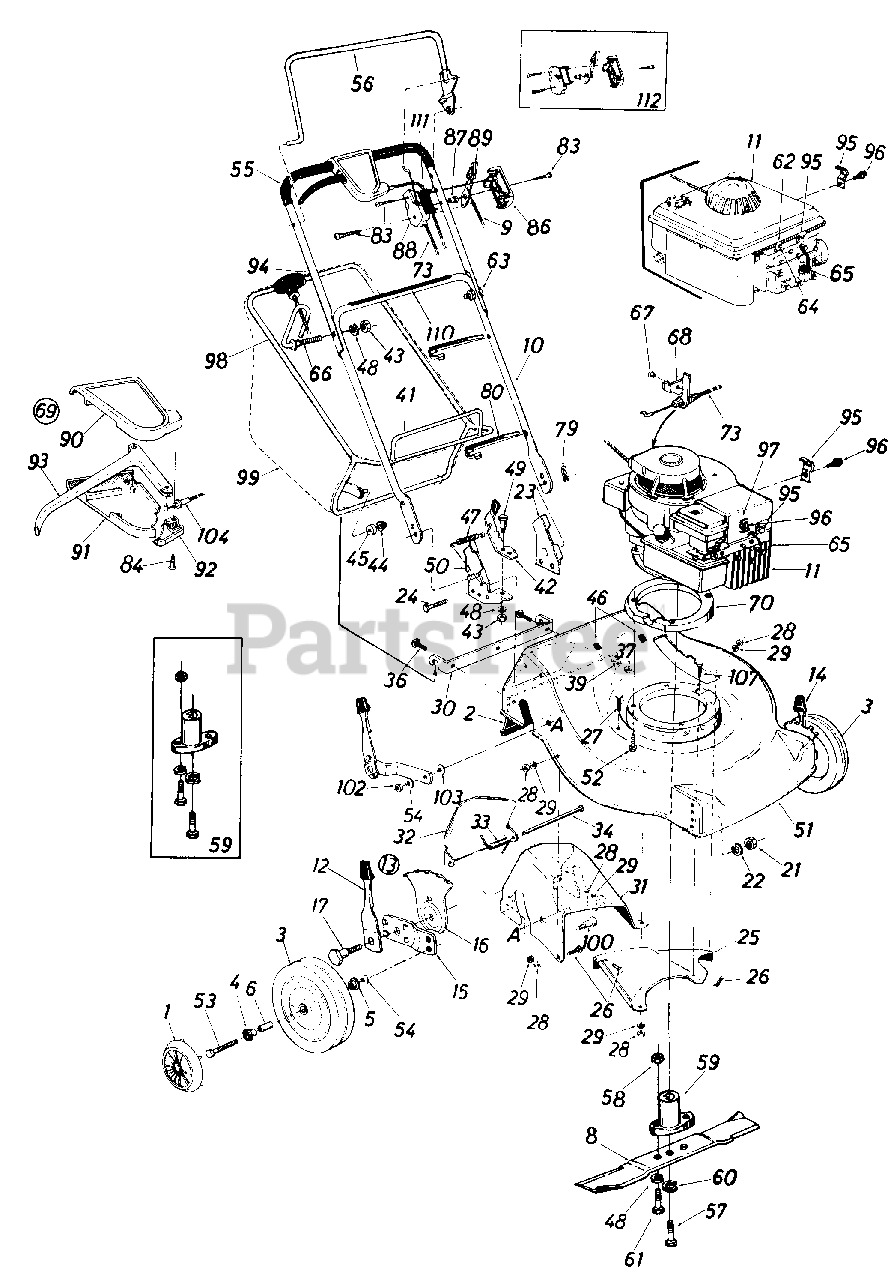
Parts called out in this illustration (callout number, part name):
1	Hub Cap
2	Rear Flap Ass'y.
3	Front Wheel Ass'y
4	Bearing
5	Bearing
6	Spacer
8	22" Blade
9	Throttle Control Wire-58"
10	Lower Handle
11	Engine
12	Spring Lever Ass'y.
13	Height Adj. Ass'y Comp.-R . H
14	Height Adj. Ass y. Comp.-L. H .
15	Pivot Bar
16	Index Plate
17	Shld. Bolt .50" Dia. x .357
21	Hex Nut 3/8-16 Thd.
22	Bell-Wash. .39" I.D. x 1.38"
23	Handle Bracket-L.H.
24	Hex Self-Tap Screw 1/4" x .62" Lg.
25	Rear Baffle-L.H.
26	Carriage Bolt 1/4-20 x .50"
27	Hex Bolt 1/4-20 x .88" Lg.
28	Hex Nut 1/4-20 Thd.*
29	L-Wash. 1/4" I.D.
30	Hitch Bracket
31	Rear Chute Baffle
32	Chute Door
33	Torsion Spring
34	Hinge Pin
36	Carr. Bolt 1/4-20 x .75" Lg.
37	Sems Nut 1/4-20 Thd.
39	Flat Wash. .285" I.D.
43	Hex Nut 5/16-18 Thd.
44	Push Cap
45	Plastic Roller
47	Extension Spring
48	L-Wash. 5/16" I.D.
49	Shoulder Bolt
50	Handle Bracket-R.H.
51	22" Deck Ass'y
52	Hex Self-Tap Screw 3/8-16 x 1.00" Lg.
53	Axle Bolt
54	Belleville Washer
56	Control Handle
57	Hex Bolt 3/8-24 x 2.25"
58	Hex Nut 5/16-24 Thread
59	Blade Adapter Kit
60	L-Wash. 3/8" I.D.-H.D.
61	Hex Bolt 5/16-24 x 1.00"
62	Casing Clamp
63	Carr. Bolt 5/16-18 x 1.38"
64	Hex B-Tap Scr. #10 x .62"
65	Spark Plug Boot
66	Rope Guide Bolt
67	Pop Rivet
68	Control Bracket
69	Clutch Control Housing Comp.
70	Engine Mount Cover
73	Control Cable-43"
79	Cotter Pin 5/16
80	Cable Tie
83	Truss Mach. Scr. #12 x 1.5"
84	Self-Tap Scr. #10 x 1.0" Lg.
86	Control Panel Half
87	Control Disc Pin
88	Clutch Panel Half
89	Throttle Control Lever
90	Control Cover Half-Upper
91	Control Cover Half-Lower
92	Cable Mounting Cap
93	Control Lever
94	Upper Handle
95	Casing Clamp
96	Hex B-Tap Scr. #10 x .38"
97	Casing Clamp
98	Catcher Upper Frame
99	Grass Bag (without Flip Top)
100	Shoulder Bolt
102	Hex Jam Nut 3/8-16 Thd.
103	Belleville Washer
104	Clutch Cable-50"
107	Hex Self-Tap Screw 1/4-20 x.75" Lg.
110	Instruction Label-Handle
111	Control Label-Throttle
112	Control Housing Comp.
